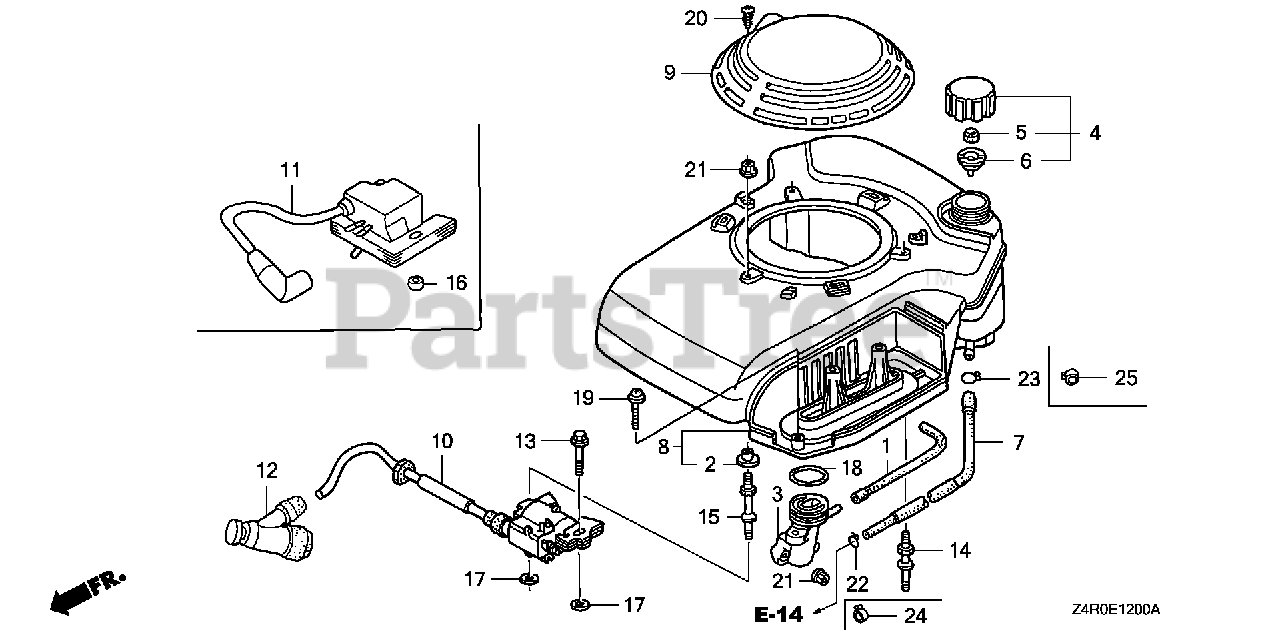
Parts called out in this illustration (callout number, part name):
1	TUBE, BREATHER
2	COLLAR, AIR CLEANER (TOYO ROKI)
3	ELBOW, AIR CLEANER
4	CAP ASSY., FUEL TANK
5	SPONGE, FUEL CAP BREATHER
6	GASKET, FUEL CAP
7	TUBE ASSY., FUEL TANK
7	TUBE ASSY., FUEL TANK (FKM)
8	COVER, FAN *NH1* (BRAKE) (BLACK)
9	HOOD, FAN COVER *NH1* (GRAINED FINISH) (BLACK)
11	COIL ASSY., IGNITION
13	BOLT, FLANGE (6X28) (CT200)
14	BOLT, STUD (BRAKE)
15	BOLT, STUD (IGNITION COIL)
16	COLLAR, SPECIAL
18	O-RING (33.3X3.5)
19	SCREW-WASHER (6X35)
20	SCREW, TAPPING (4X20)
21	NUT, FLANGE (6MM)
22	CLIP, TUBE (B8)
23	CLIP, TUBE (C9)
24	CLAMP, TUBE (D8)
25	CLAMP, TUBE (D8.5)
